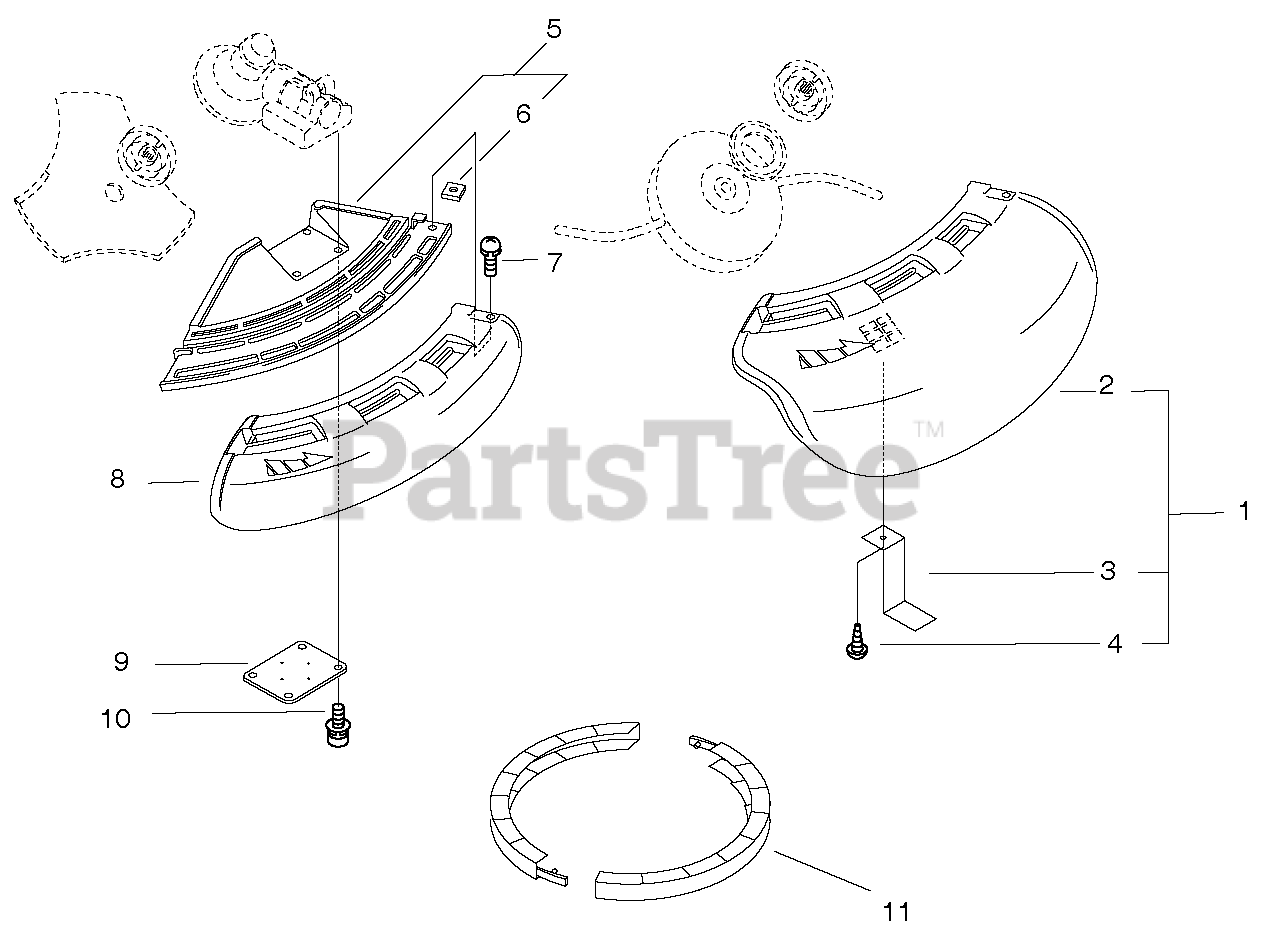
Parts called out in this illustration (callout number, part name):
1	DEBRIS SHIELD ASSY
2	SHIELD, DEBRIS
3	CUTTER, LINE
4	SCREW, TAPPING 5×12
5	BRACKET ASSY, SHIELD
6	NUT M5
7	BOLT 5×22
8	SHIELD, BLADE
9	PLATE, SHIELD
10	BOLT 5×25
11	COVER, BLADE
